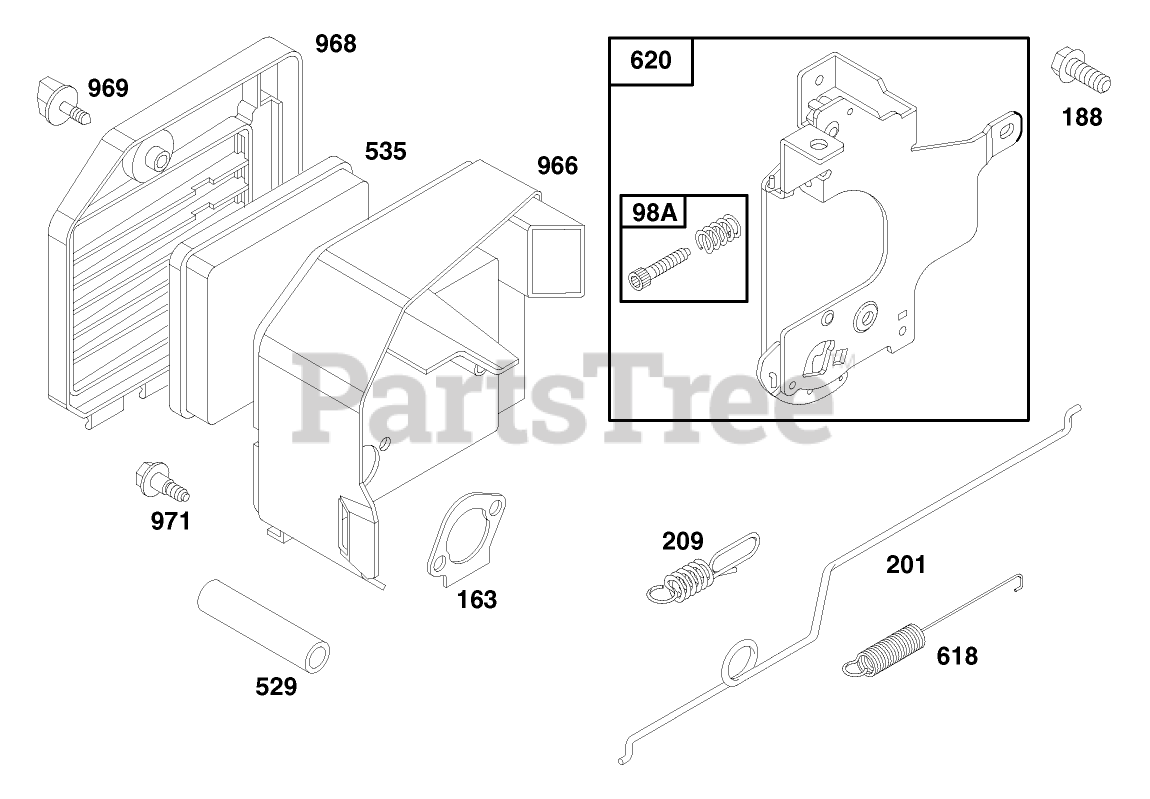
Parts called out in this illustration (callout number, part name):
98A	SPEED ADJUST. SCREW ASM
163	AIR CLEANER GASKET
201	GOVERNOR LINK
209	GOVERNOR SPRING
529	TUBE - BREATHER
535	FILTER ELEMENT
618	RETURN SPRING
966	AIR CLEANER BASE
969	AIR CLEANER SCREW
971	AIR CLEANER SCREW
